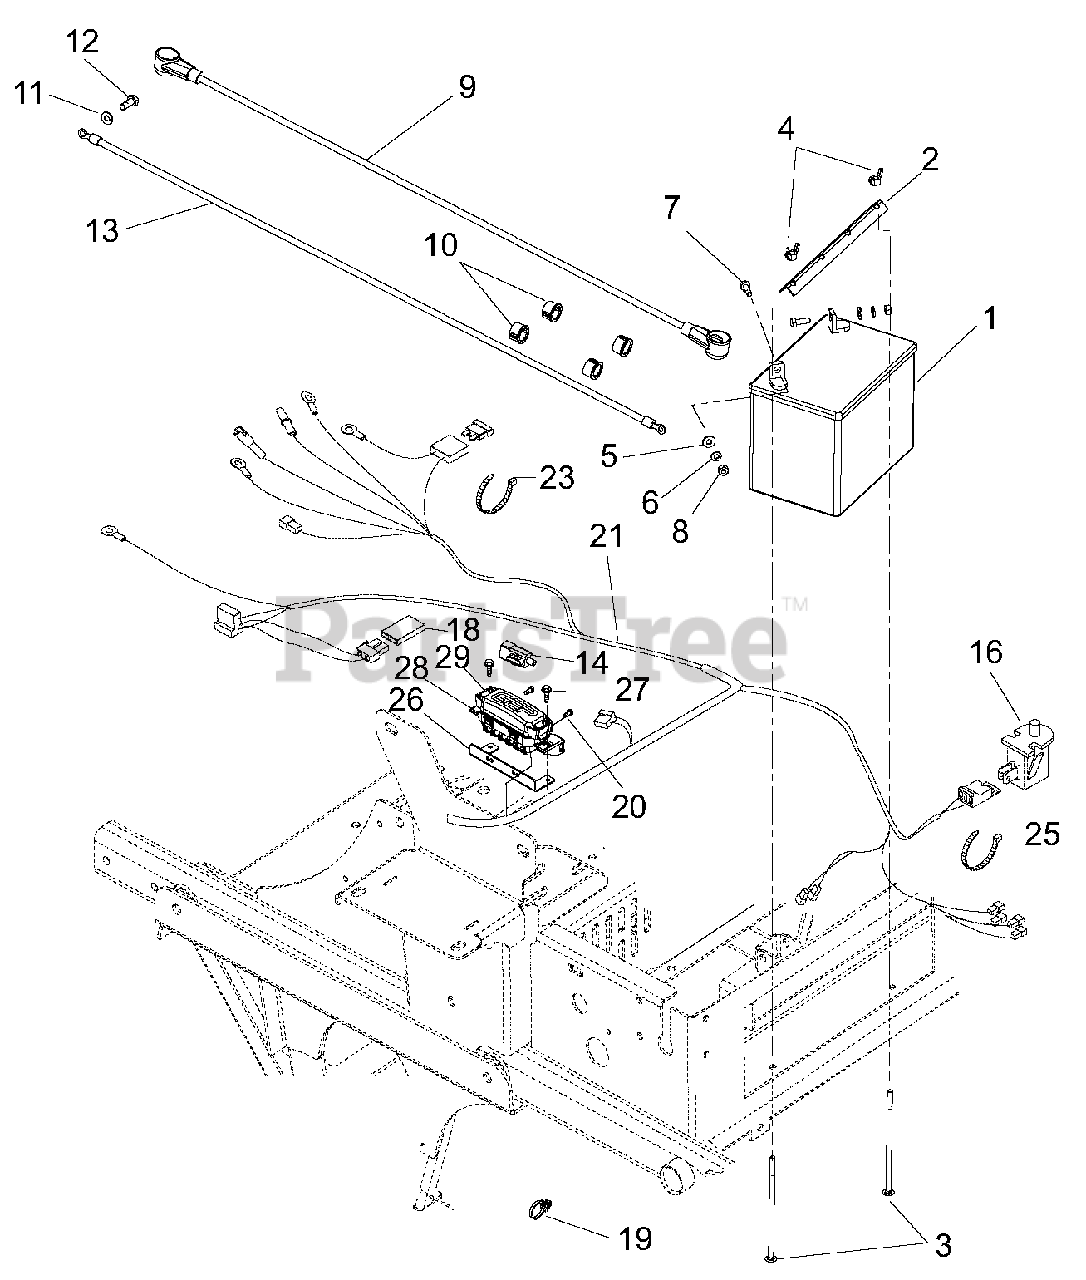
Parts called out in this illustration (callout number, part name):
1	BATTERY, 300 CCA 10U1L
2	Hold Down
3	Bolt, Round Head Square Neck .25-20 x 7.50
4	Nut, Locking Wing .250-20
5	Washer, Flat-Steel .281 x .62 x .065
6	Washer, Locking .25 x .062 Regular
7	Bolt, Hex .25-20 x .75 Grade 5
8	Nut, Hex .25-20
9	Cable, POS Battery w/Boots 6 x 35
10	Bushing, Panel Snap .687 x .875 x .56
11	Washer, Locking .31 x .078 Regular
12	Bolt, Hex M8-1.25 x 20
13	Cable, Negative Battery 35.0"
14	Switch, Snap-In - N.O./N.O.
16	Switch, Snap Mounting (Included with Seat)
18	Diode, Connector Shell (Included with Harness)
19	Cable Tie with TREE (.25 HOLE)
20	Bolt, Hex M6-1.0X25
21	Harness, PT400 Wiring
23	Cable Tie
24	Lead, Starter Solenoid
25	Cable Tie
26	Fuse Holder Mounting Bracket
27	Screw-Tapping .25-20X.50 Hex Washer Head
28	Fuse Holder (included with Harness)
29	Cover, Fuse Holder
